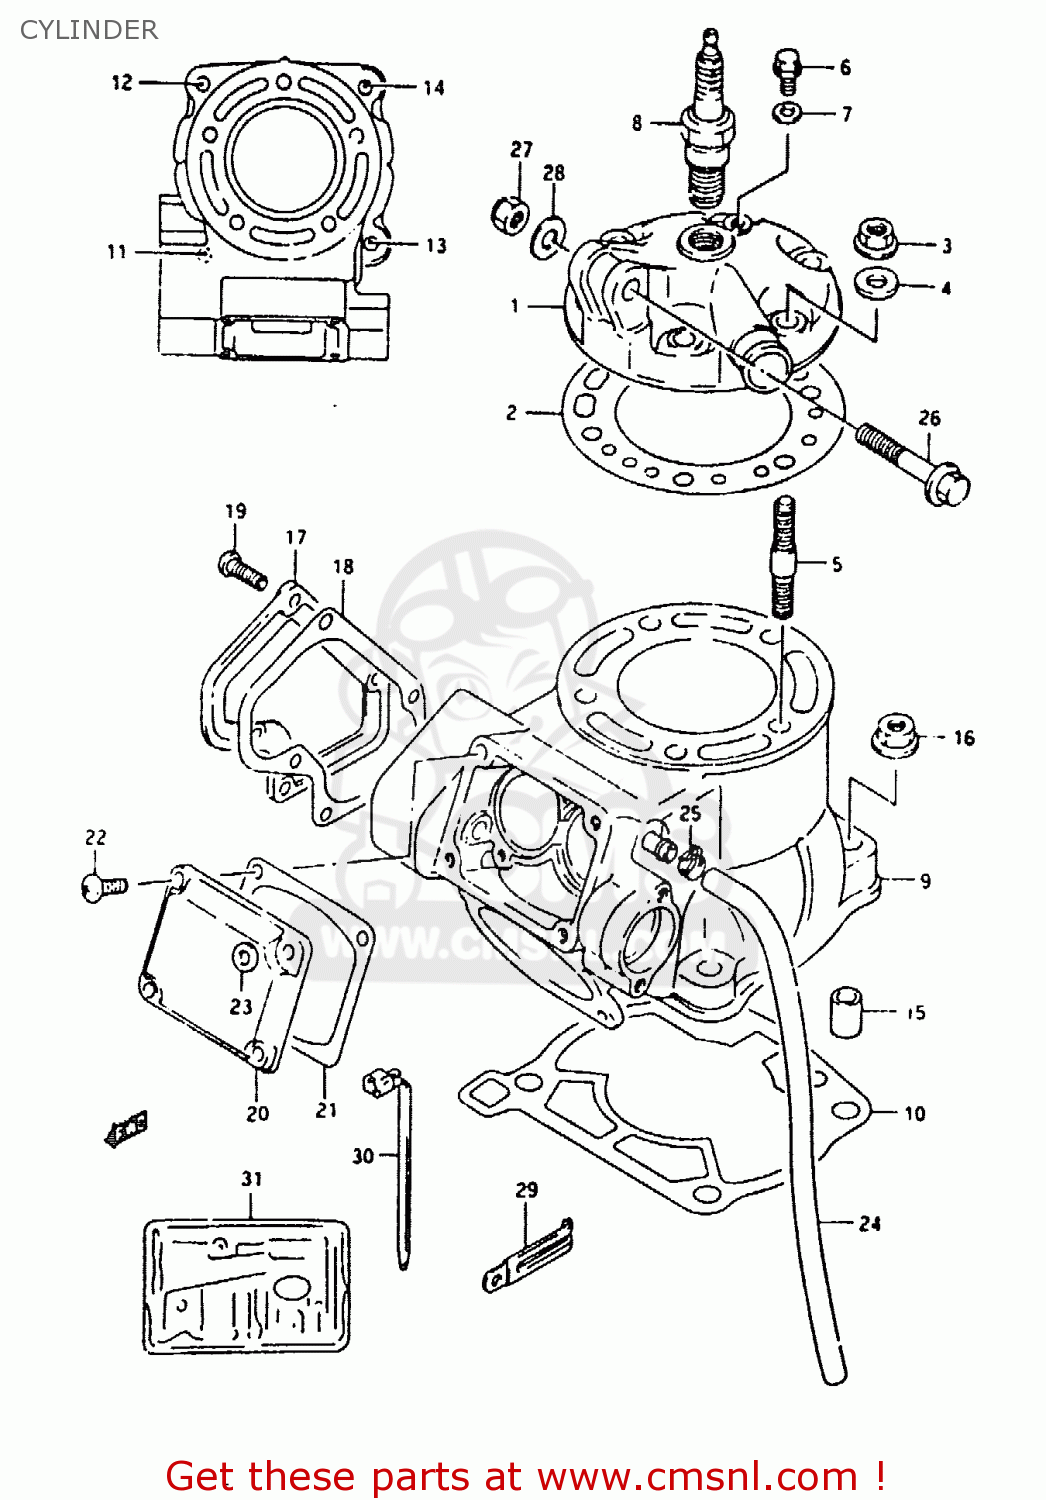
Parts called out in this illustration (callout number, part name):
1	HEAD,CYLINDER
2	GASKET,CYLINDER HEAD
3	NUT
4	WASHER
5	BOLT,STUD
6	UNION
7	GASKET(6.2X11X1).2 (NAS)
8	SPARK PLUG BR9EV
9	CYLINDER
10	GASKET,CYLINDER (NAS)
11	STUD 10X30
12	STUD BOLT
13	STUD BOLT (L:40)
14	BOLT,STUD
15	PIN
16	NUT
17	COVER,CYLINDER NO.1
18	GASKET,CYLINDER COVER (NAS)
19	BOLT
20	COVER,CYLINDER
21	GASKET,CYLINDER COVER (NAS)
22	SCREW
23	GASKET(5.3X9.3X1.2) (NAS)
24	HOSE
25	CLIP
26	BOLT 8X45
27	NUT
28	WASHER
29	CLAMP
30	CLAMP(L:125)
31	GASKET SET (MCA)
